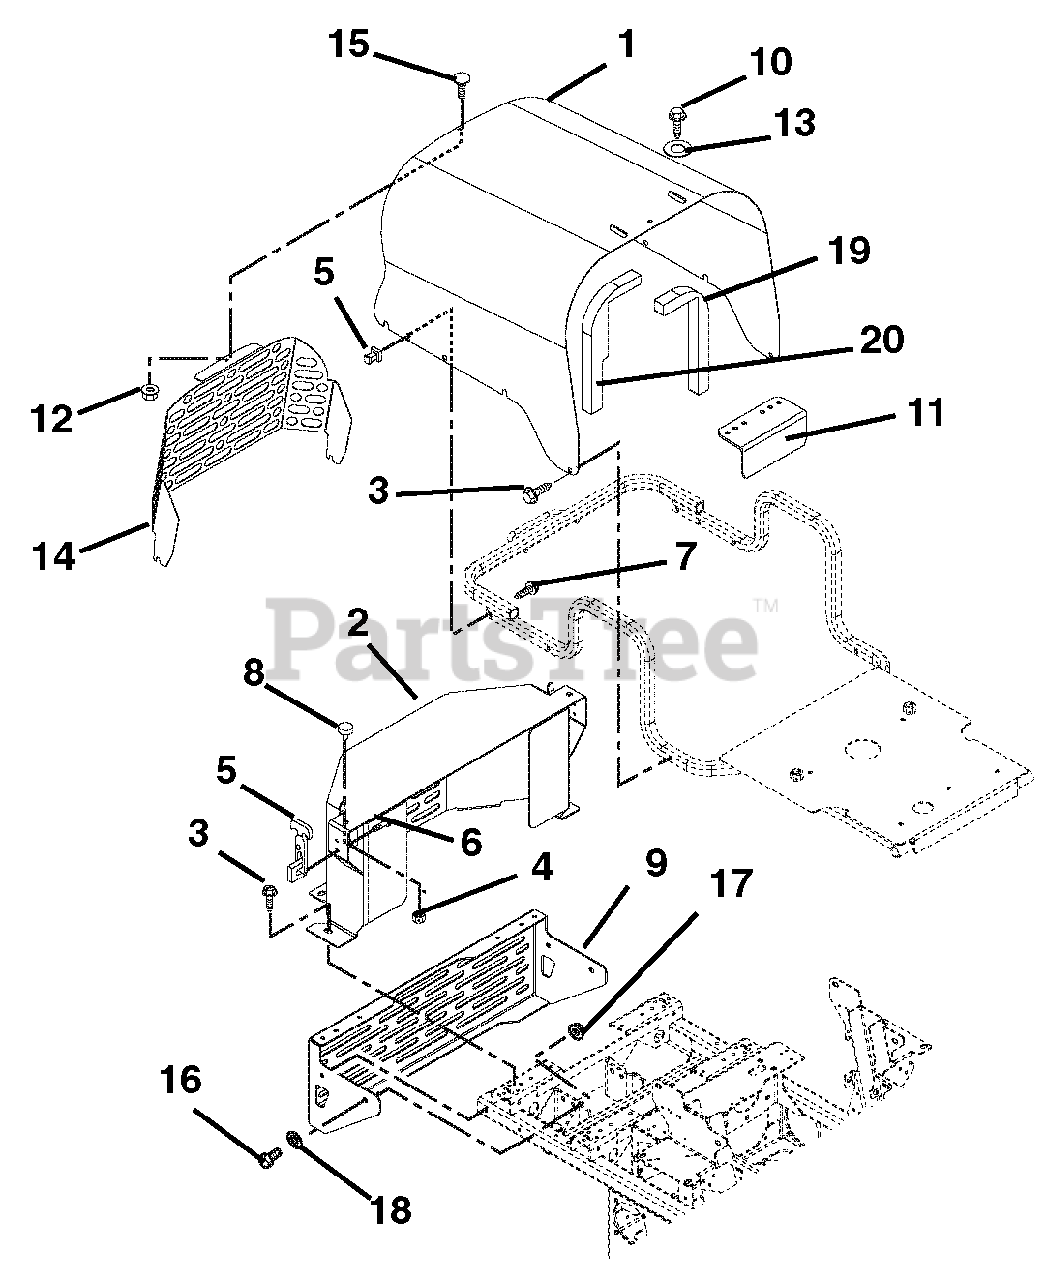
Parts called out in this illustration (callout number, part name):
2	Diesel Belt Guard
3	Screw, Tapping .38-16 x .75 Hex Washer Head
4	Nut, Spin Lock, Flange .312-18
5	Latch, Rubber
6	Screw, Machine 10-24 x .50 Hex Washer Head
7	Screw, Machine 10-24 x 1.50 Hex Washer Head
8	Bumper, Rubber
9	Bumper, Weldment, Rear Diesel
10	Screw, Tapping .25-20 x .50 Hex Washer Head
11	Guard, Radiator Cap
12	Nut, Locking Top Flange .25-20
13	Washer, Flat Steel .281 x .62 x .065
14	Guard, Hood
15	Bolt, Round Head Square Neck .25-20 x .50 Grade 5
16	Bolt, Hex .38-16 x 2.75 Grade 5
17	Nut, Locking Top Flange .38-16
18	Washer, Flat Steel .406 x .812 x.065
19	Dam, Left Side Foam Air
20	Dam, Right Side Foam Air
